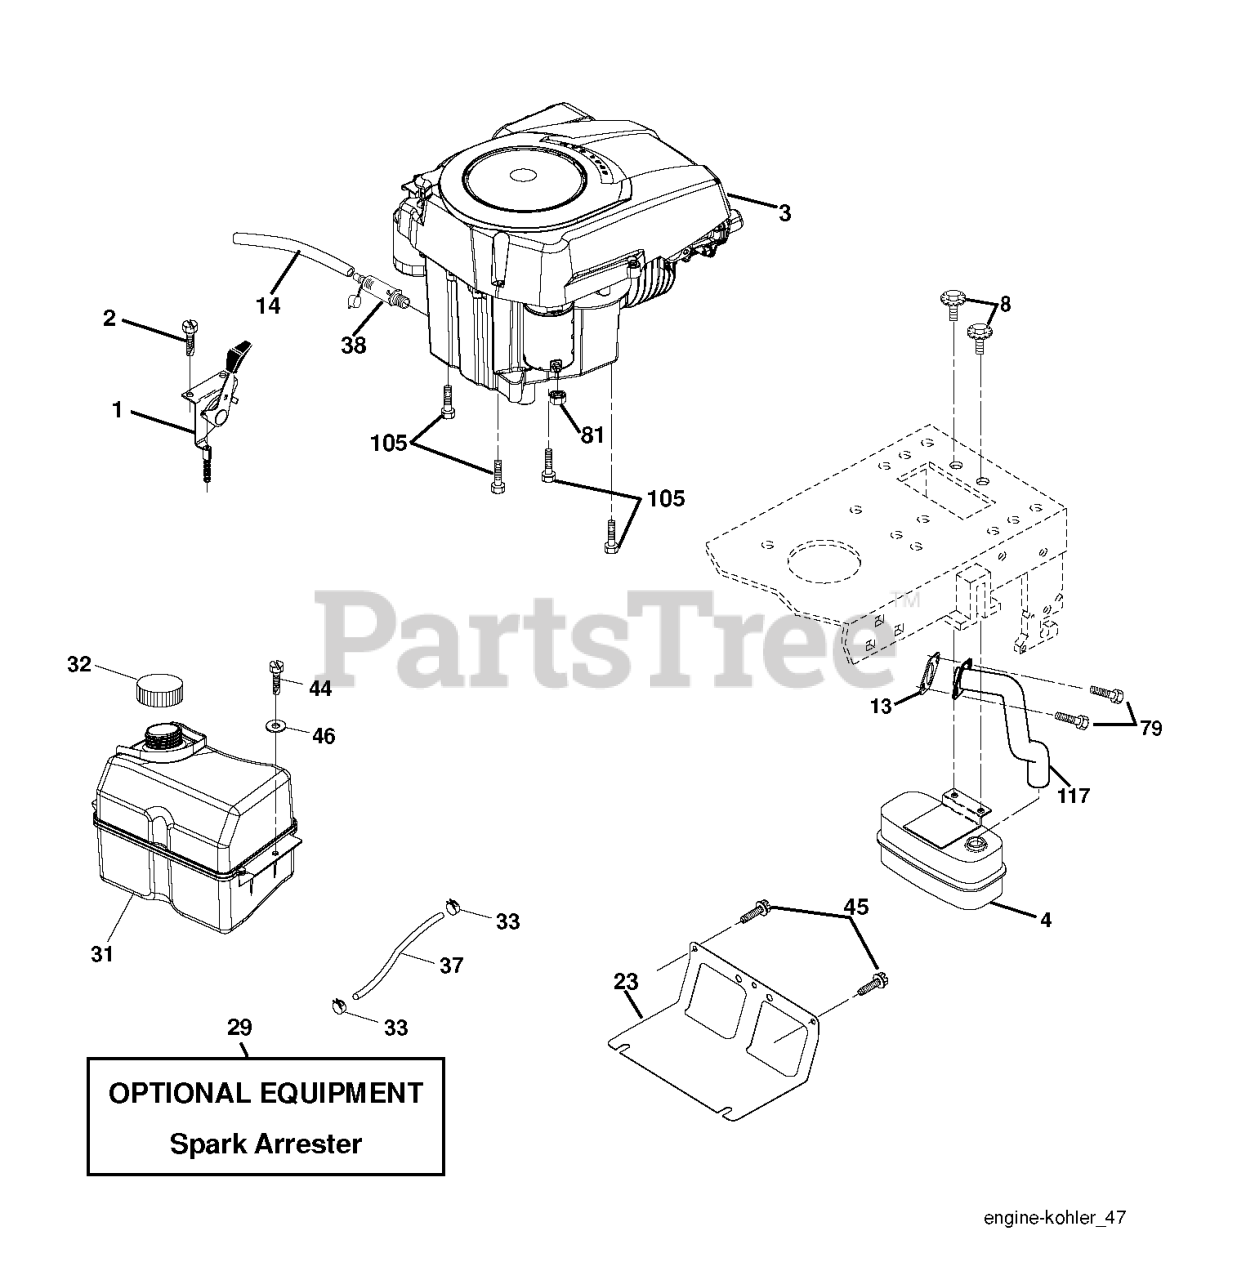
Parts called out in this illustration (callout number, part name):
1	CONTROL.TH/CK.C.
2	SCREW.#10 X 0.750.BOS
4	MUFFLER.SINGLE.CYL.KOHL/B&S
8	BOLT.5/16-18UNCX3/4 W/SEMS.BLK
13	GASKET.EXHAUST.KOHLER
14	TUBE, DRAIN OIL ASM.
23	SHIELD.BROWNING.DBR.GUARD
29	KIT.SPARK ARRESTOR 794945 B&S
31	RP TANK FUEL FRT 1.5 GAL
32	FUEL CAP
33	HOSE CLAMP
37	LINE.FUEL.20
38	PLUG DRAIN OIL EASY
44	SCREW HEXWSHR 1/4-20X3/4
45	SCREW, 3/8-16X3/4
79	SCREW.SOCKET HD.5/16-1
81	NUT
105	SCREW 3/8-16X1
117	RP.TUBE.EXHAUST.KOHL.COURAGE
